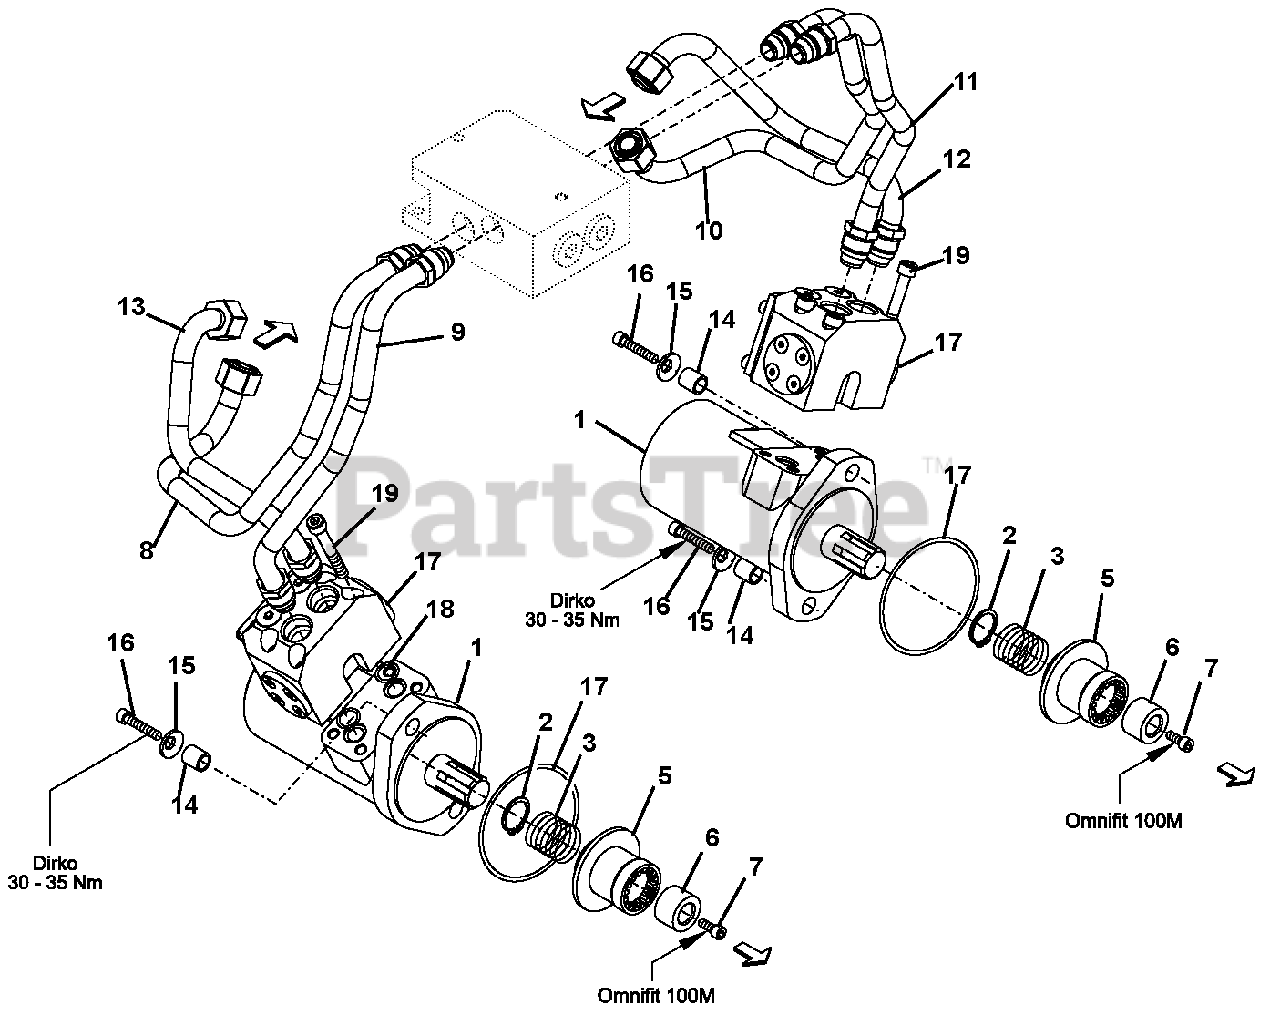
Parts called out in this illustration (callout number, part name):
1	Motor, Hydraulic, 157CCM
2	Circlip, 24 1,20
3	Pressure Spring
6	Screw, 1/4 x 5/8" UNC
7	Pipe, Hydraulic Assembly
8	Pipe, Hydraulic Assembly
9	Pipe, Hydraulic Assembly
10	Pipe, Hydraulic Assembly
11	Pipe, Hydraulic Assembly
12	Pipe, Hydraulic Assembly
14	Washer, FORM Z 10.2/16.1 x 1.6
15	Screw, D912 M10 x 30
16	O-Ring, 78 x 3
17	Valve Control
18	O-Ring, D3770 12,37 x 2,62
19	Bolt, Cylindrical, M8 x 60
